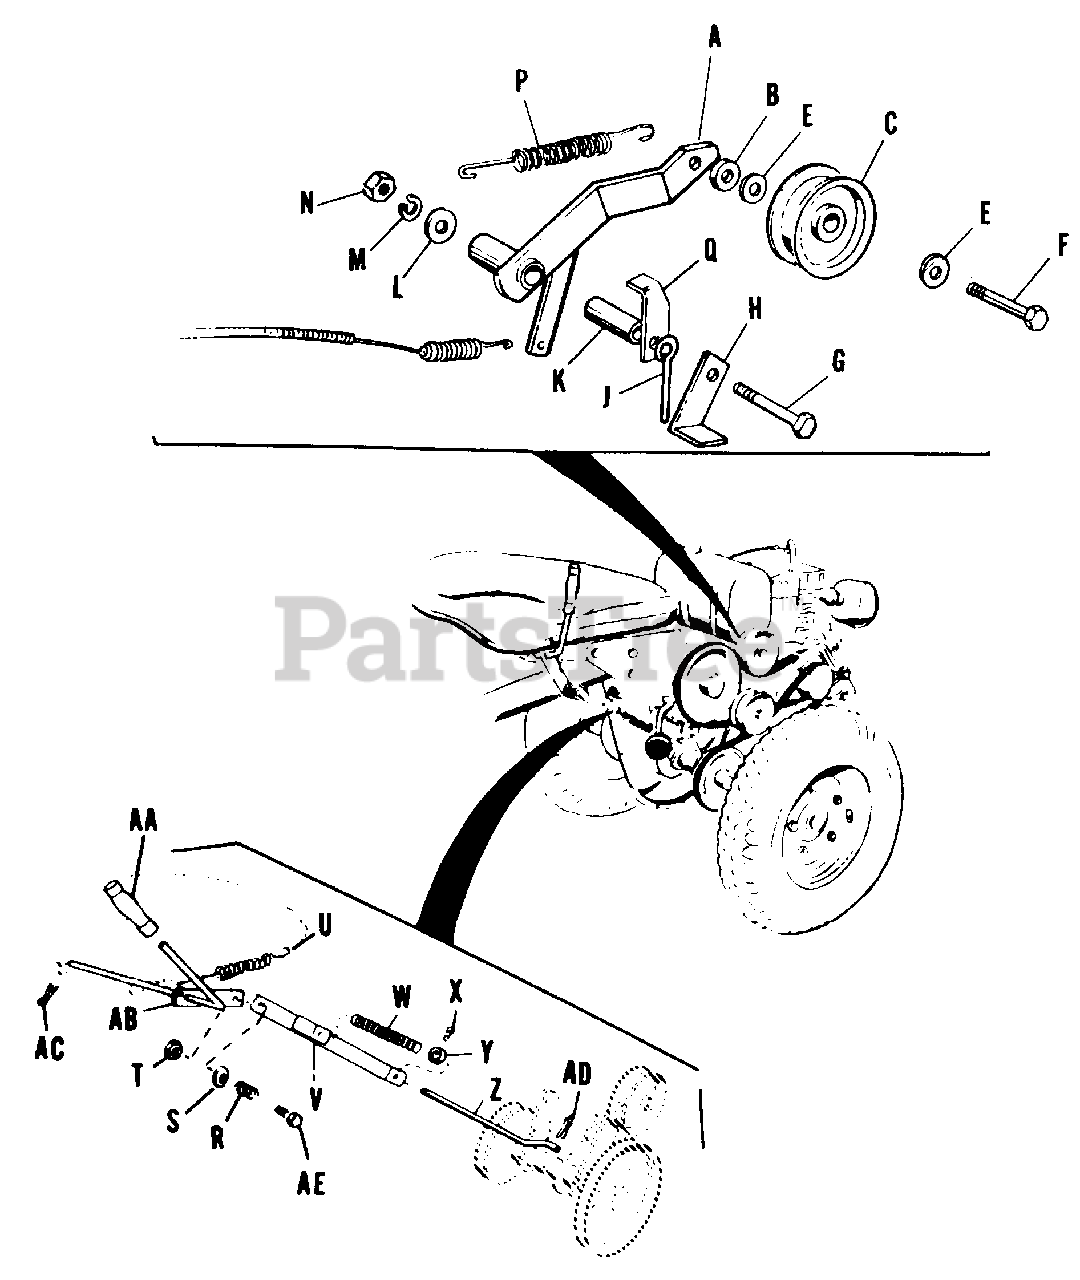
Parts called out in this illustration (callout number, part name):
A	Idler Lever Assembly
C	Idler Pulley
E	Washer, Plain, 5/16
F	Capscrew, Hex Hd., 3/8 x 1 1/2
G	Capscrew, Hex Hd., 3/8 x 3
H	Guide, Belt
J	Pin, Lock
K	Spacer, Idler Lever
L	Washer, Plain, 3/8
M	Washer, Lock 3/8
N	Nut, Hex, Full, 3/8
P	Spring, Idler Lever
Q	Stop, Lever
S	Washer, Plain, 5/16
T	Nut, Lock, Full Hex, 3/8-16
V	Guide Assembly, Clutch Rod
X	Set Screw, Sq. Hd., 1/4 x 3/8
Z	Rod, P.T.O. Clutch
AB	Lever Assembly, Clutch
AC	Cotter Pin, 3/8 x 1
AD	Cotter Pin, 3/32 x 5/8
AE	Capscrew, Hex Hd., 3/8 x 1 1/4
